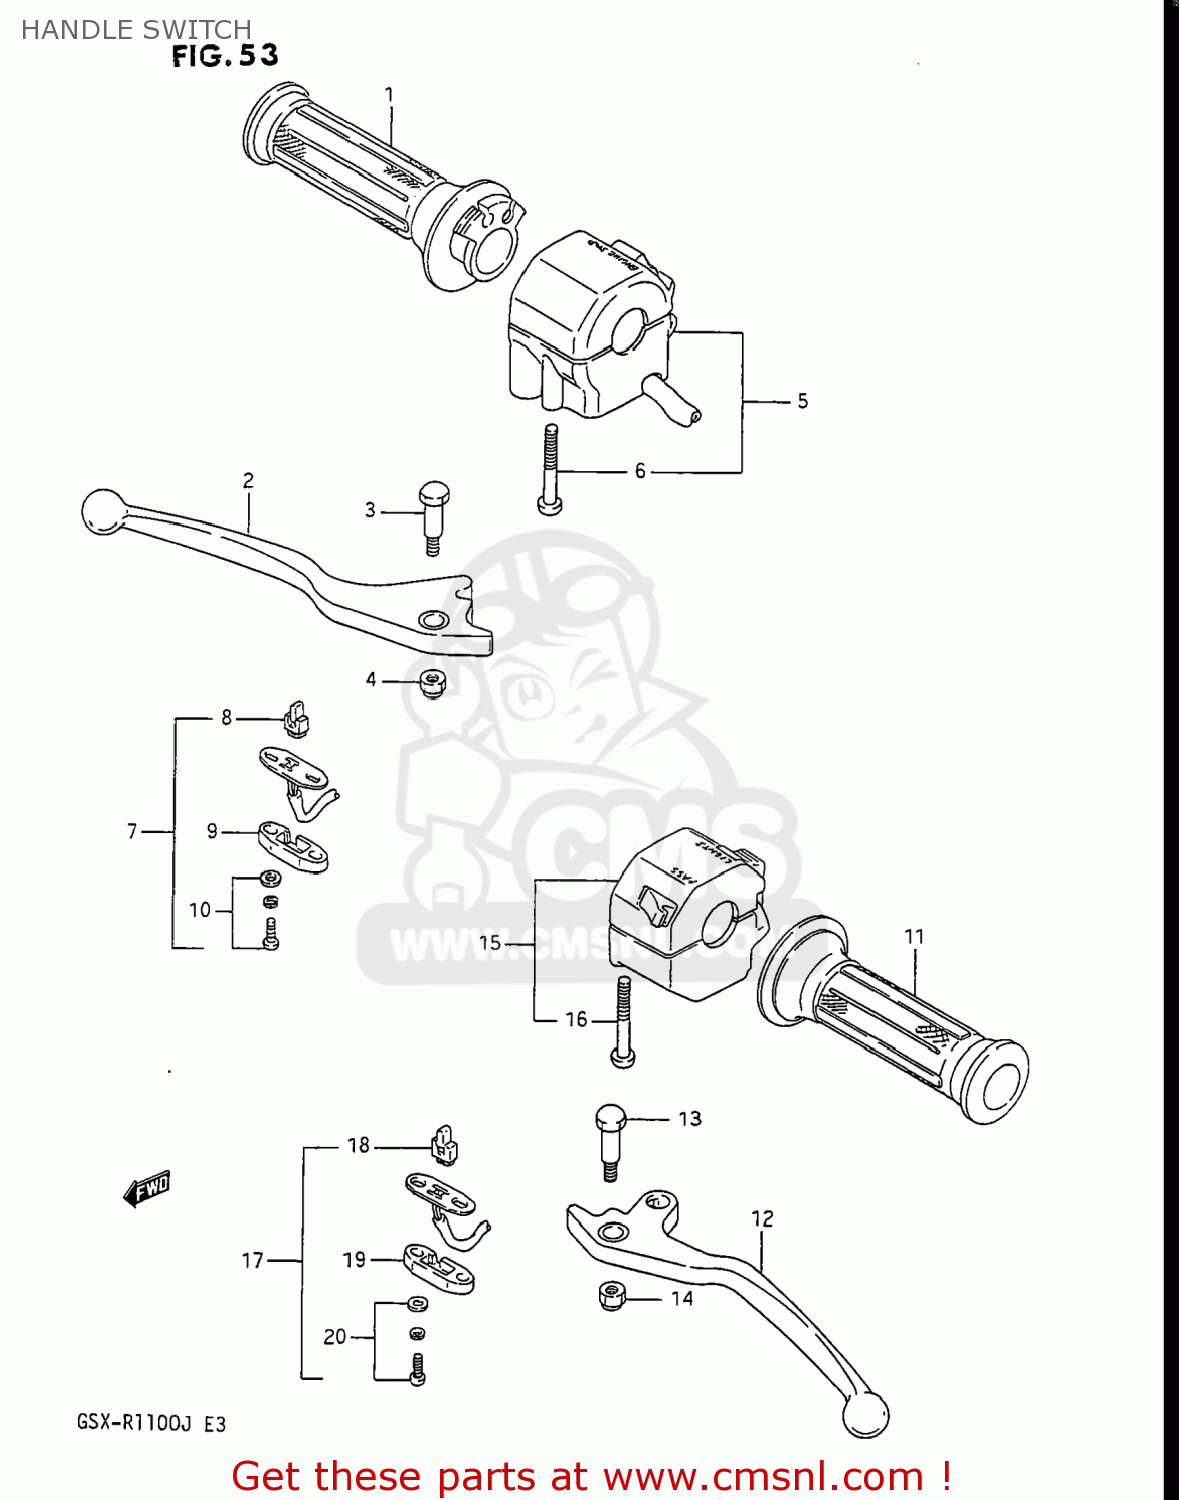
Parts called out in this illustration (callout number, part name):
1	GRIP,THROTTLE
2	LEVER,BRAKE
3	BOLT,LEVER
4	NUT
5	SWITCH ASSEMBLY,HANDLE,RIGHT
6	SCREW, 5X45
7	SWITCH ASSY,STOP
8	CONTACT,SWITCH
9	COVER,FR BK TERMINAL BASE
10	SCREW
11	GRIP,L
12	LEVER,CLUTCH (BLACK)
13	BOLT,LEVER
14	NUT
15	SWITCH ASSEMBLY,HANDLE,LEFT
16	SCREW
17	SWITCH ASSEMBLY,CLUTCH
18	CONTACT,SWITCH
19	COVER,FR BK TERMINAL BASE
20	SCREW
